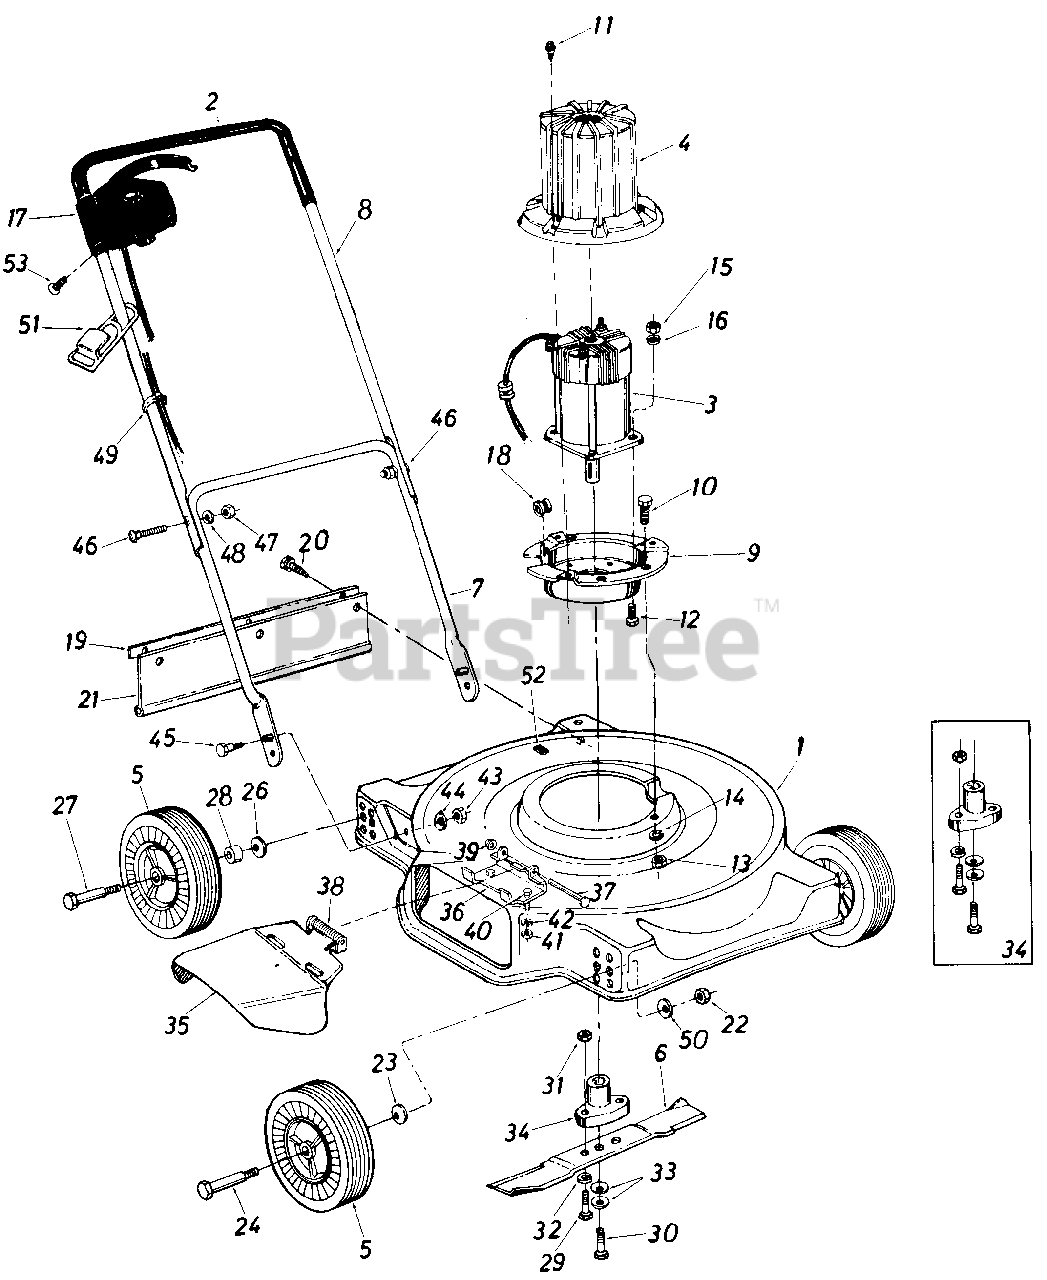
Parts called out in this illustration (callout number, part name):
1	20" Deck Ass'y.
4	Motor Shroud
5	Wheel Ass'y. Comp. 7 x 1.50
6	20" Blade
7	Lower Handle
8	Upper Handle
9	Drive Housing Brkt.-L.H.
10	Hex Bolt 3/8-16 x 1.00" Lg.
11	Hex Wash Hd. "F" Tap Scr. #10-32 x .314" Lg.
12	Hex Bolt 1/4-20 x 1.00" Lg.
13	Hex Nut 3/8-16 Thd.*
14	L-Wash. 3/8" I.D.
15	Hex Nut 1/4-20 Thd.
16	L-Wash. 1/4" I.D.
17	Control w/Cord
18	Cord Restraint
19	Retaining Strip
20	Hex Wash. Hd. AB-Tap Scr. 1/4 x.62" Lg.
21	Rear Flap Ass'y. 4.65 x 17.2" Lg.
22	Hex Nut 3/8-16 Thd.*
23	Bell-Wash. .400" I.D. x .88"O.D.
24	Shld. Bolt .498" Dia. x 1.450" Lg.
26	Bell-Wash. .400" I.D. x .88"O.D.
27	Shld. Bolt .498" Dia. x 1.830" Lg.
28	Spacer. 511" I.D. x .70" O.D. x.38" Lg.
29	Hex Bolt 5/16-24 x 1.00" Lg. (Grade 5)
30	Hex Bolt 5/16-24 x .75" Lg.
31	Hex Nut 5/16-24 Thd.*
32	L-Wash. 5/16" I.D.
33	Bell-Wash. .345" I.D. x .88" O.D.
34	Blade Adapter Kit
35	Chute Deflector Ass'y. Comp
36	Deflector Hinge Plate
37	Hinge Pin
38	Torsion Spring
39	Push On Flange Nut
40	Hex Bolt 1/4-20 x .50" Lg.
41	Hex Nut 1/4-20 Thd.
42	L-Wash. 1/4" I.D.*
43	Hex Nut 5/16-18 Thd.
44	Bell-Wash. .345" I.D. x .88"O.D.
45	Shld. Bolt .437" Dia. x .268" Lg.
46	Curved Hd. Carr. Bolt 5/16-18 x 1.38" Lg.
47	Hex Nut 5/16-18 Thd.
48	L-Wash. 5/16" I.D.
49	Cable Tie
50	Bell-Wash. .39" I.D. x 1.13"O.D.
51	Restraint
52	Plastic Plug
53	Truss Mach. AB-Tap Scr.
